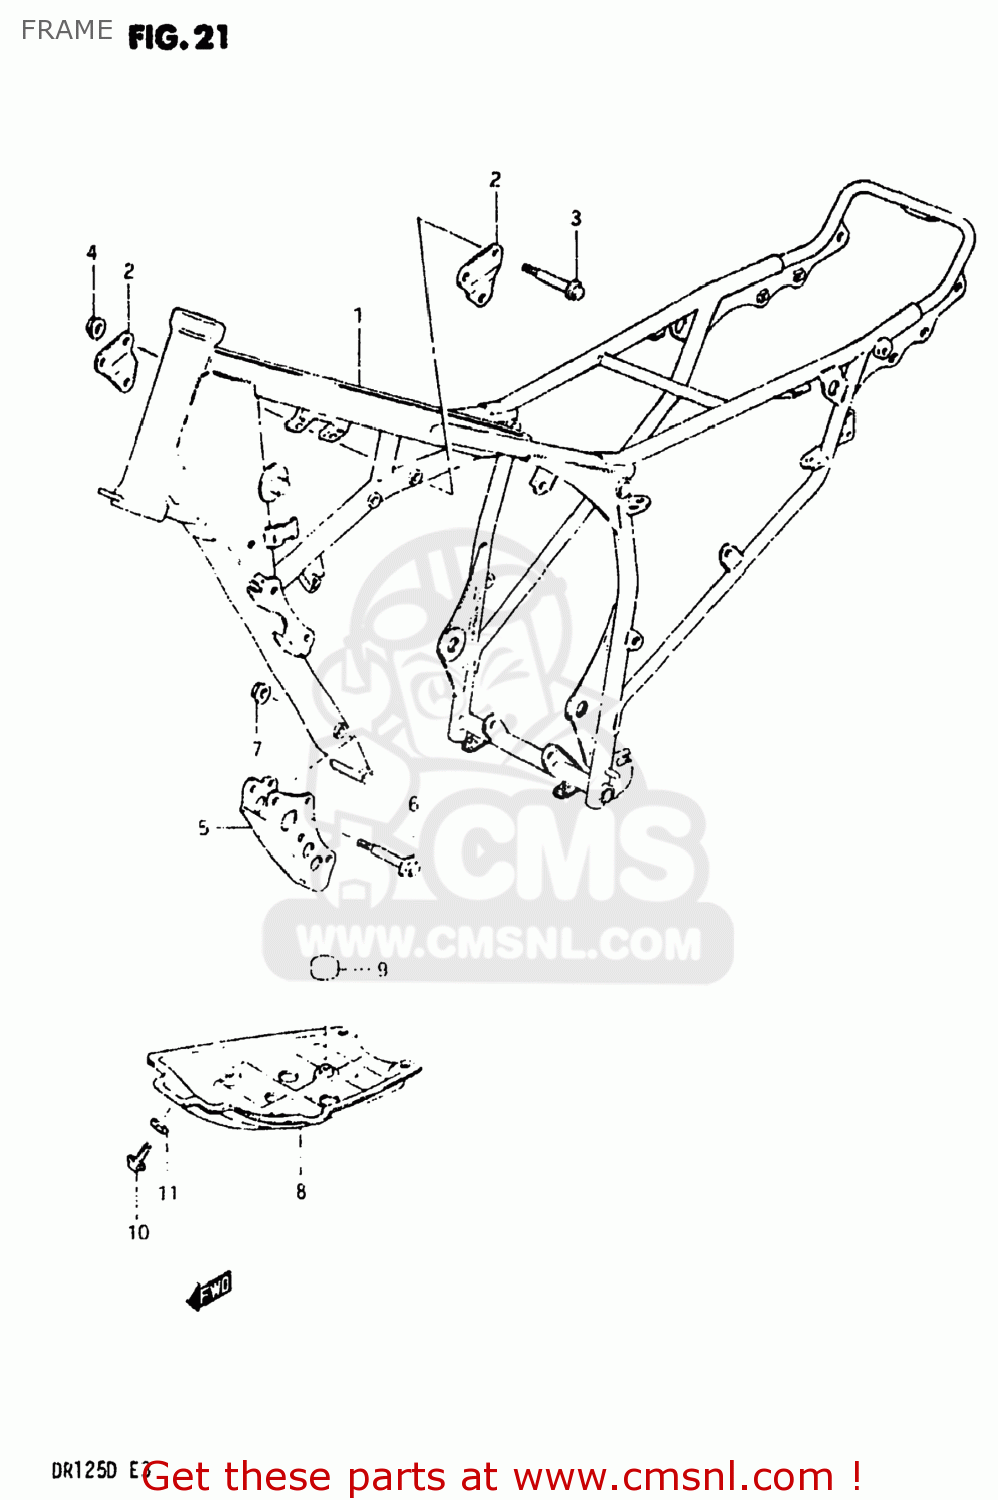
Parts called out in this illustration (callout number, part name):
1	FRAME
2	PLATE,ENGINE MOUNTING
3	BOLT
4	NUT
5	PLATE,ENGINE MOUNTING
6	BOLT
7	NUT
8	PROTECTOR,ENGINE
9	CUSHION
10	BOLT
11	WASHER
